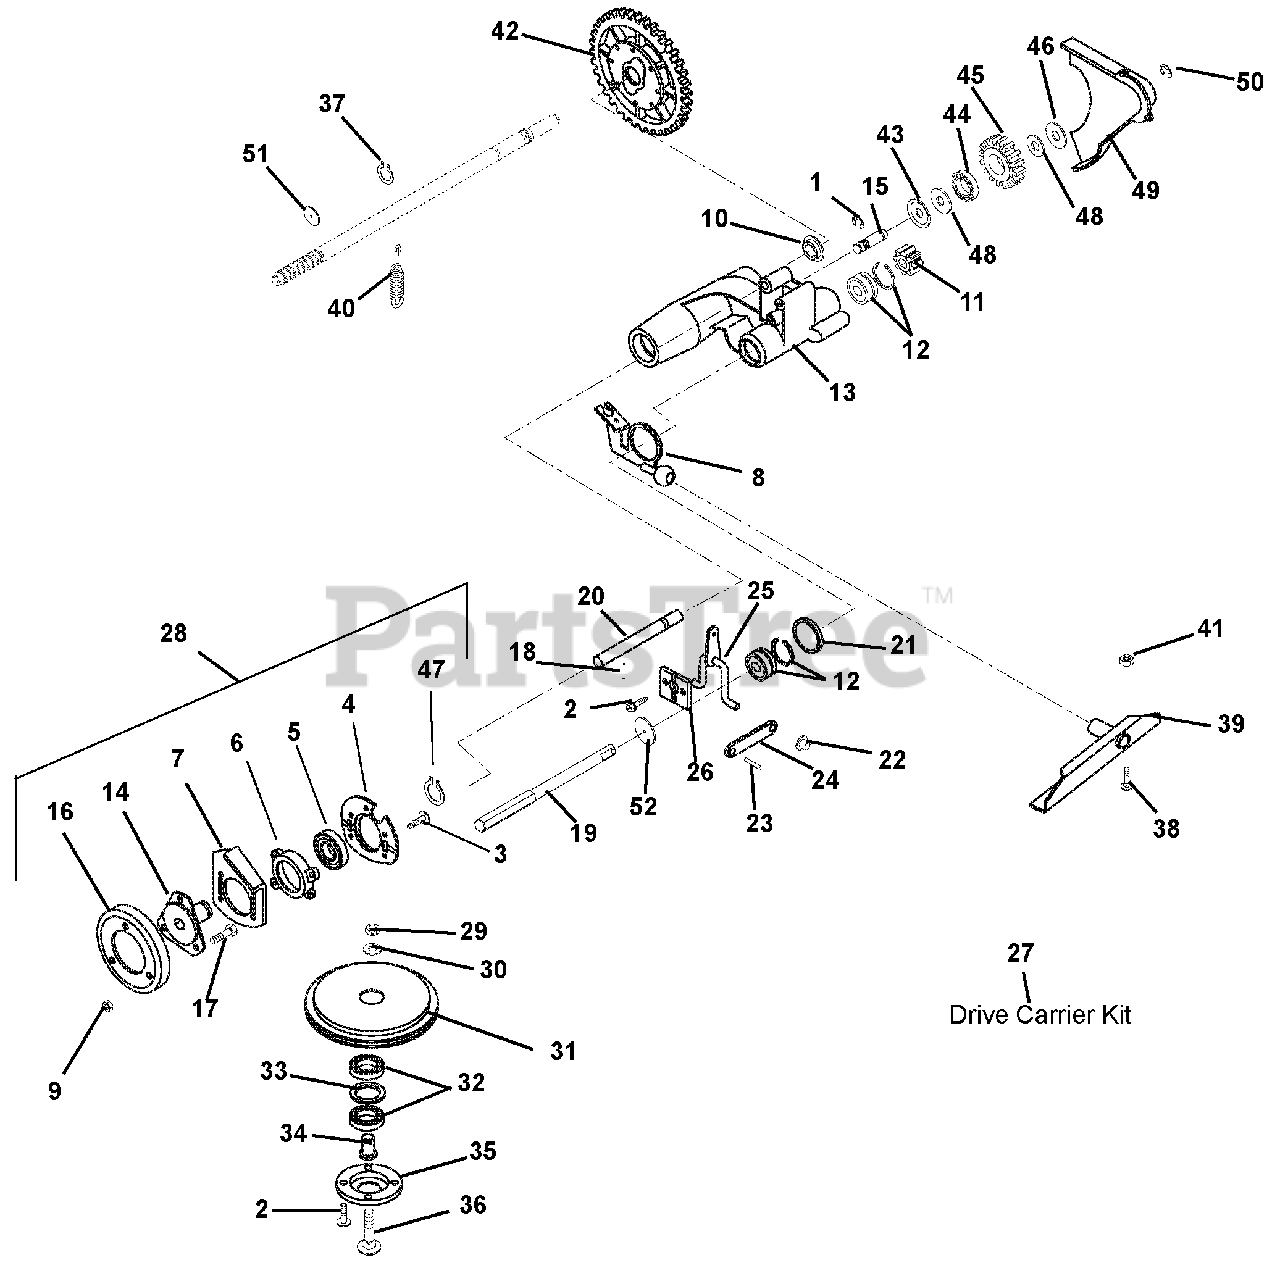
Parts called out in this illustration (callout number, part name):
1	RG-RTNG-EXT .438X.035
2	@SCR-TAP 12-24X.50 HWH TR YWZC
3	SCR-TAP 5HX-0.8X16MM H-FL-YWZC
4	BEARING RETAINER
5	BRG-BALL 1.0X2.0X.56 (1641)
6	BEARING RETAINER
7	PLATE, BEARING
8	ACTUATOR, WBLM DRIVE
9	@NUT-LK-CTR .25-20 YWZC
10	BRG-BALL .625X1.378X.44
11	PINION, D-SHAFT
13	DRIVE MOUNT
14	FRICTION WHEEL HUB
15	IDLER SHAFT
16	DISC, FRICTION - 730 MAT'L
17	@BLT-HEX .25-20X.50 GR5 YWZC
18	PIN-ROLL .188X.88
19	SHAFT, FRICTION DISK
20	ROD - GUIDE
21	WSHR-FL-STL 1.390X2.00X.020 PL
22	PUSH NUT, .25
23	PIN-ROLL .125X.50
24	SHIFT LINK
25	SHIFT ARM WELDMENT
26	RETAINER PLATE
27	KIT, LM DRIVE CARRIER
28	KIT, COM. DRIVE CONVERSION
29	@NUT-LK-CTR .31-18 YWZC
30	WSHR-FL-STL .328X.87X.179 YWZC
31	FRICTION SHEAVE
33	WSHR-FL-STL 1.062X1.344X.032PL
34	SPINDLE - BEARING
35	RETAINER - BEARING
36	@BLT-RDHDSQNK .31-18X1.75 G5YZ
37	RG-RTNG-EXT .579X.035
38	@BLT-RHDSSQNK .31-18X.62 G5YZ
39	PIVOT CHANNEL WELDMENT
40	SG-TENS .051X.60X2.25 WLD 7.0
41	@NUT-LK-TOP-FLG .31-18 YWZC
42	DIFFERENTIAL ASSEMBLY
43	RETAINER
45	IDLER GEAR
46	WSHR-FL-STL.531X1.00X.063 YWZC
47	RG-RTNG-EXT 1.00X.042
48	WSHR-FL-STL .52X.827X.062 YWZC
49	COVER, GEAR
50	RG-RTNG-EXT .438X.035
51	WSHR-FL-STL .630X1.250X.062 YZ
52	WSHR-FL-STL .505X.880X.072 YWZ
